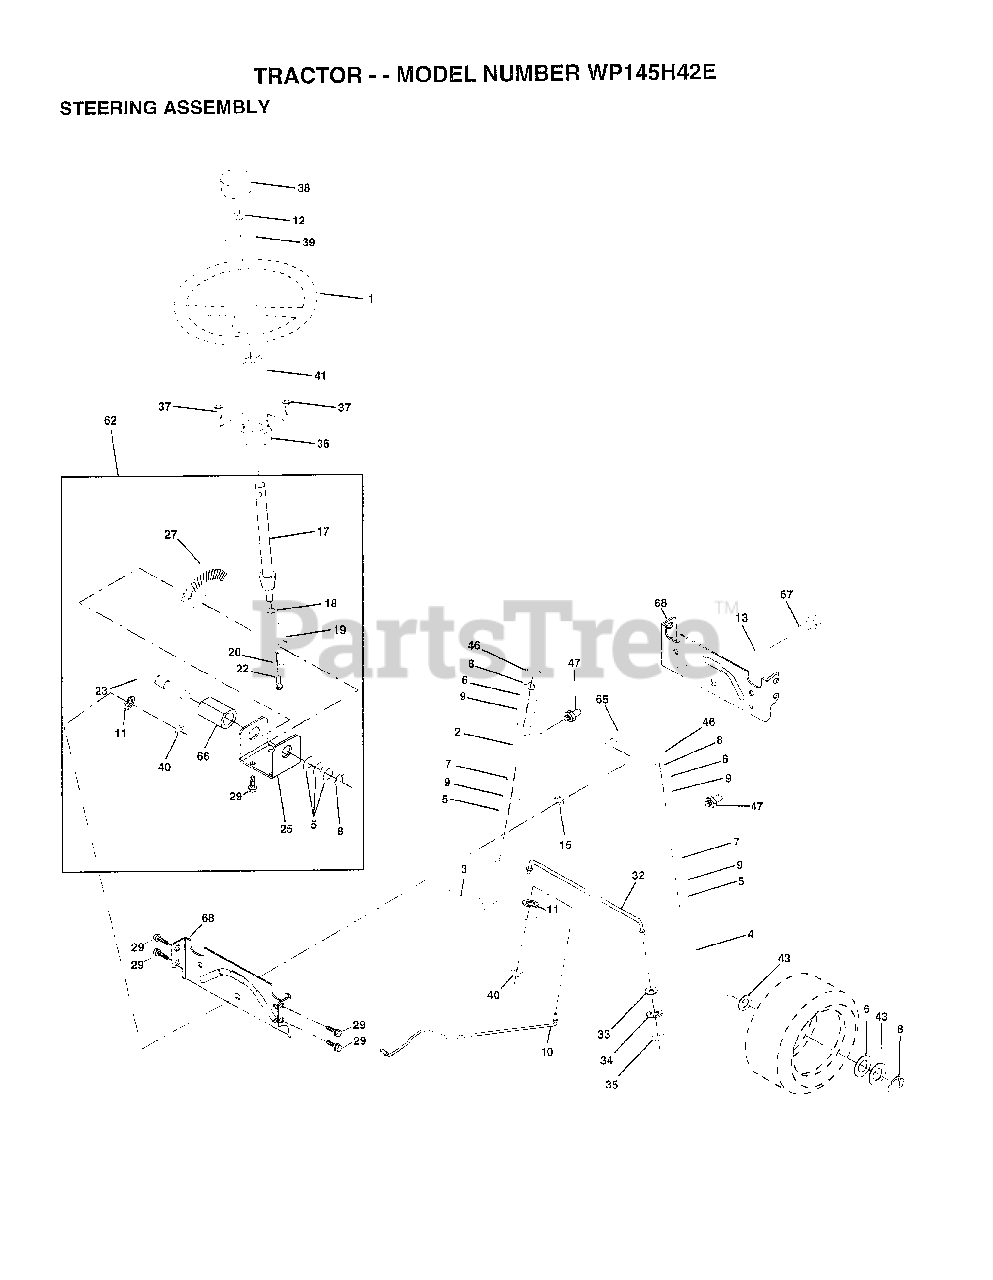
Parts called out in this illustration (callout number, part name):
2	AXLE ASM
3	SPINDLE.ASM.LH
4	"SPINDLE ASM,RH"
5	WASHER .T
6	WASHER
7	WASHER
8	RING
9	COL. SRTG. BEAR.
10	DRAGLINK-STAMPED
11	LOCKWASHER
13	BEARING AXLE
15	"NUT-LOC,FLANGE LT"
17	SHAFT ASM STEERNG
18	THRUST WASHER
19	SUPPORT.SHAFT
22	SCREW HEX SOC1/4-
25	BRKT-STEERING
27	GEAR SECTOR
29	SCREW
32	ROD.TIE.19.75
33	WASHER M
34	LOCKWASHER
35	NUT.LOCK.5/16-24
36	BUSHING.STRG.3/4
37	"SCREW-TT,10-32 FL"
38	"INSERT,STR WHEEL"
39	WASHER
40	GRIPCO NUT
41	ADAPTER LT
46	CAP
47	ZERK M
62	KIT STEERING ASM
65	SPACER AXLE
66	"BEARING-ARM,PITMA"
67	BOLT
68	BRACE AXLE
